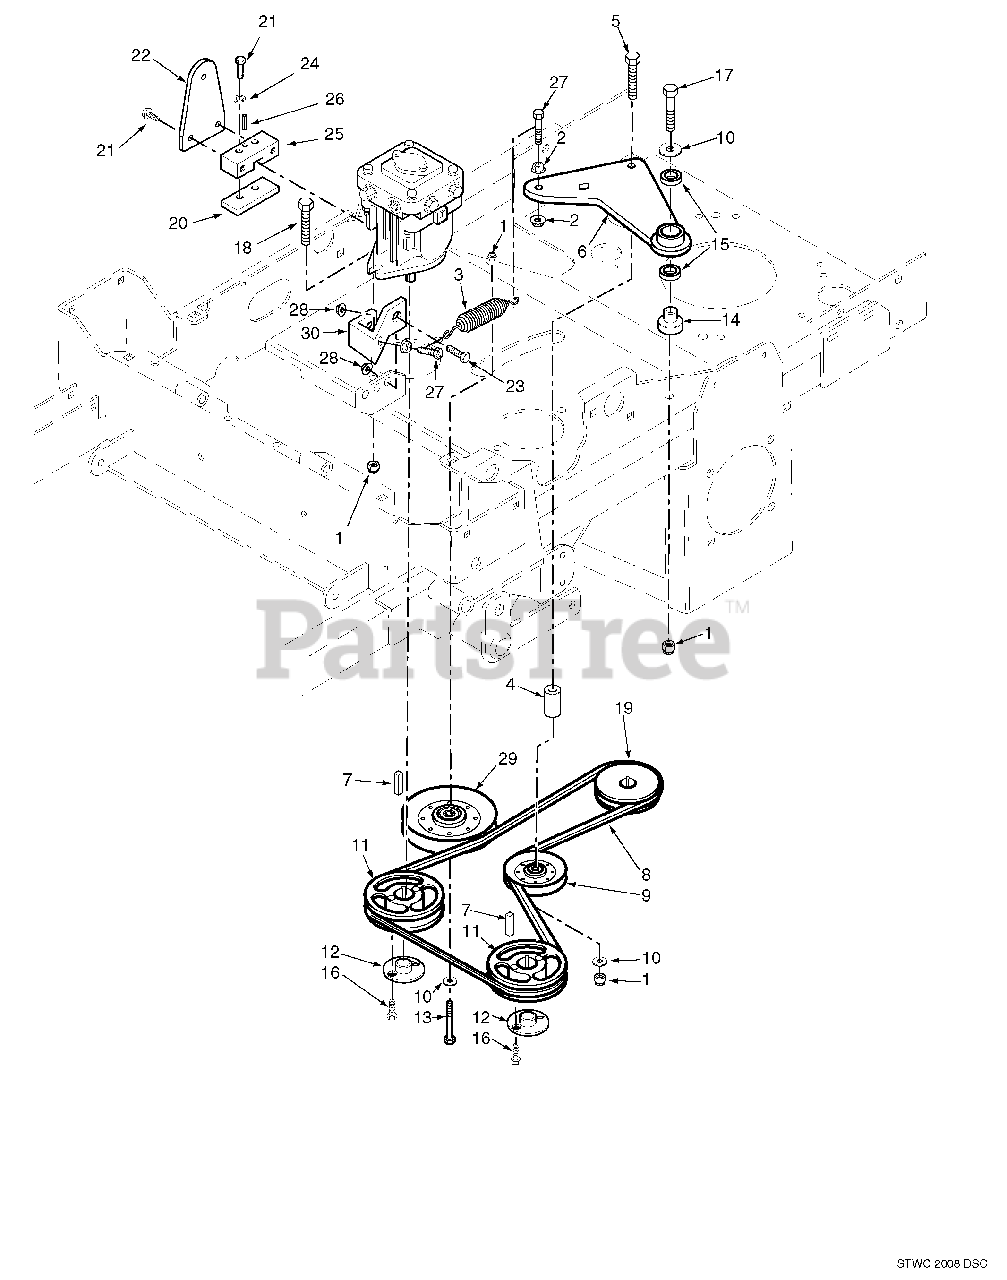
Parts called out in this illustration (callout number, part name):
1	Nut, Elastic Stop 3/8-16
2	Nut, Serr. Flng. 3/8-16
3	Spring, Pump Idler
4	Spacer
5	Bolt, Hex Hd. 3/8-16 x 2-3/4"
6	Idler Arm Assy., Pump Drive
7	Key, 5 x 5 x 25mm
8	Belt, Transmission
9	Pulley, 3-1/2" Dia. Idler
10	Flatwasher, 3/8 (.391 x .938 x .105")
11	Pulley, 5.75" OD Taper Bore
12	Hub, Tapered, 15mm Bore
13	Bolt, 3/8-16 x 2"
14	Pivot, Idler
15	Bearing
16	Bolt, Hex Hd. 1/4-20 x 1" Grd. 8
17	Bolt, Hex Hd. 3/8-16 x 2-1/2"
18	Bolt, Hex Hd. 3/8-16 x 1-1/2"
19	Pulley, 5.75" Dia. - 1.125" Bore
20	Clamp Plate
21	Hex Hd. Capscrew, 1/4-20 x 3/4"
22	Control Lever, Pump
23	Bolt, Hex Hd. 3/8-16 x 1"
24	Lockwasher, 1/4"
25	Block, Pump Control
26	Roll Pin
27	Bolt, Hex Hd. 3/8-16 x 1-1/2" Grd. 8
28	Nut, Serr. Flng. 3/8-16
29	Pulley, 5" Dia. Idler
30	Bracket
